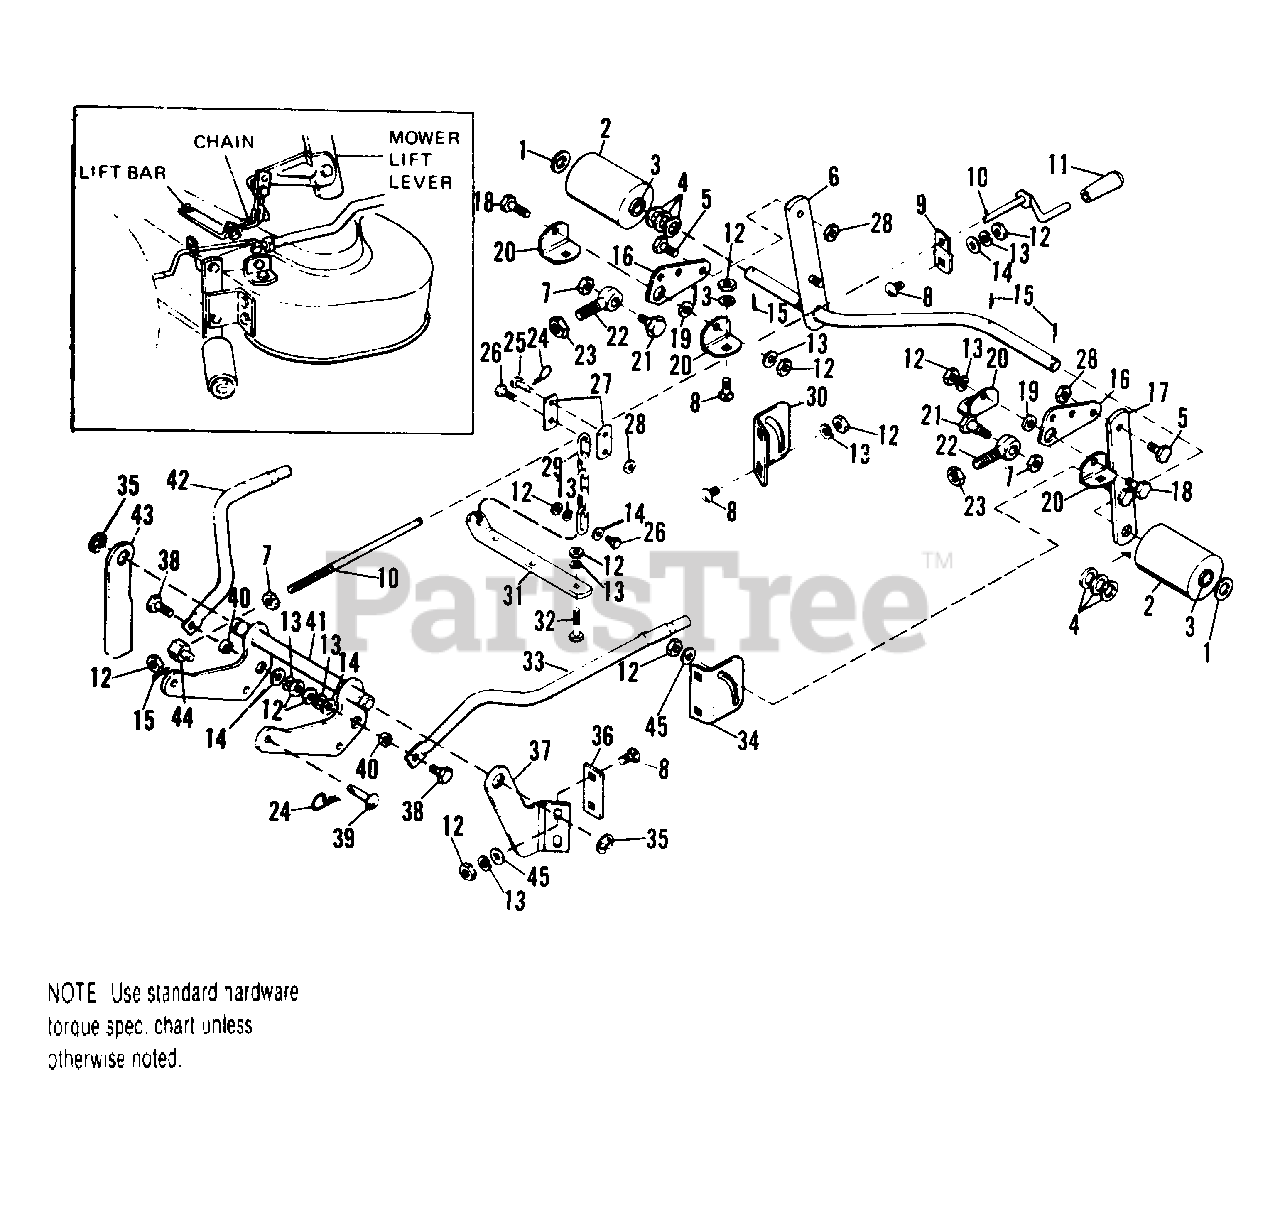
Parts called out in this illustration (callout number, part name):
2	ROLLER ASSY.
5	CAPSCREW, Hex Hd., 3/8-16 x 7/8
6	ROLLER BAR & SHAFT ASSY.
7	LOCKNUT, Hex, Jam, 3/8-16
8	BOLT, Carriage, 3/8-16 x 3/4
9	BRACKET, Screw, Adjusting
10	SCREW ASSY., Adj.
12	NUT, Hex, Full, 3/8-16
13	LOCKWASHER, 3/8
14	WASHER, Plain, 3/8
15	PIN, Cotter, 3/16 x 1
16	LEVER, Rear
17	BAR ASSY., Roller
18	CAPSCREW, Hex Hd., 3/8-16 x 1
20	BRACKET, Pivot
21	BOLT, Shoulder
23	LOCKNUT, Hex, Jam, 1/2-20
24	CLIP, Spring
26	CAPSCREW, Hex Hd., 3/8-16 x 1
27	LINK, Lift, Mower
28	LOCKNUT, Hex, 3/8-16
29	CHAIN
30	BRACKET, Roller, R.H.
31	BAR, Lift
32	CAPSCREW, Hex Hd., 3/8-16 x 3/4
33	ARM, Adjusting, L.H.
34	BRACKET, Roller, L.H.
35	RING, Retaining
36	BAR, Spacer
37	BRACKET, Front, L.H.
38	CAPSCREW, Hex Hd., 3/-16 x 1
41	HITCH ASSY., Mower
42	ARM, Adjusting, R.H.
43	BRACKET. Front, R.H.
45	WASHER, Plain, 5/16
